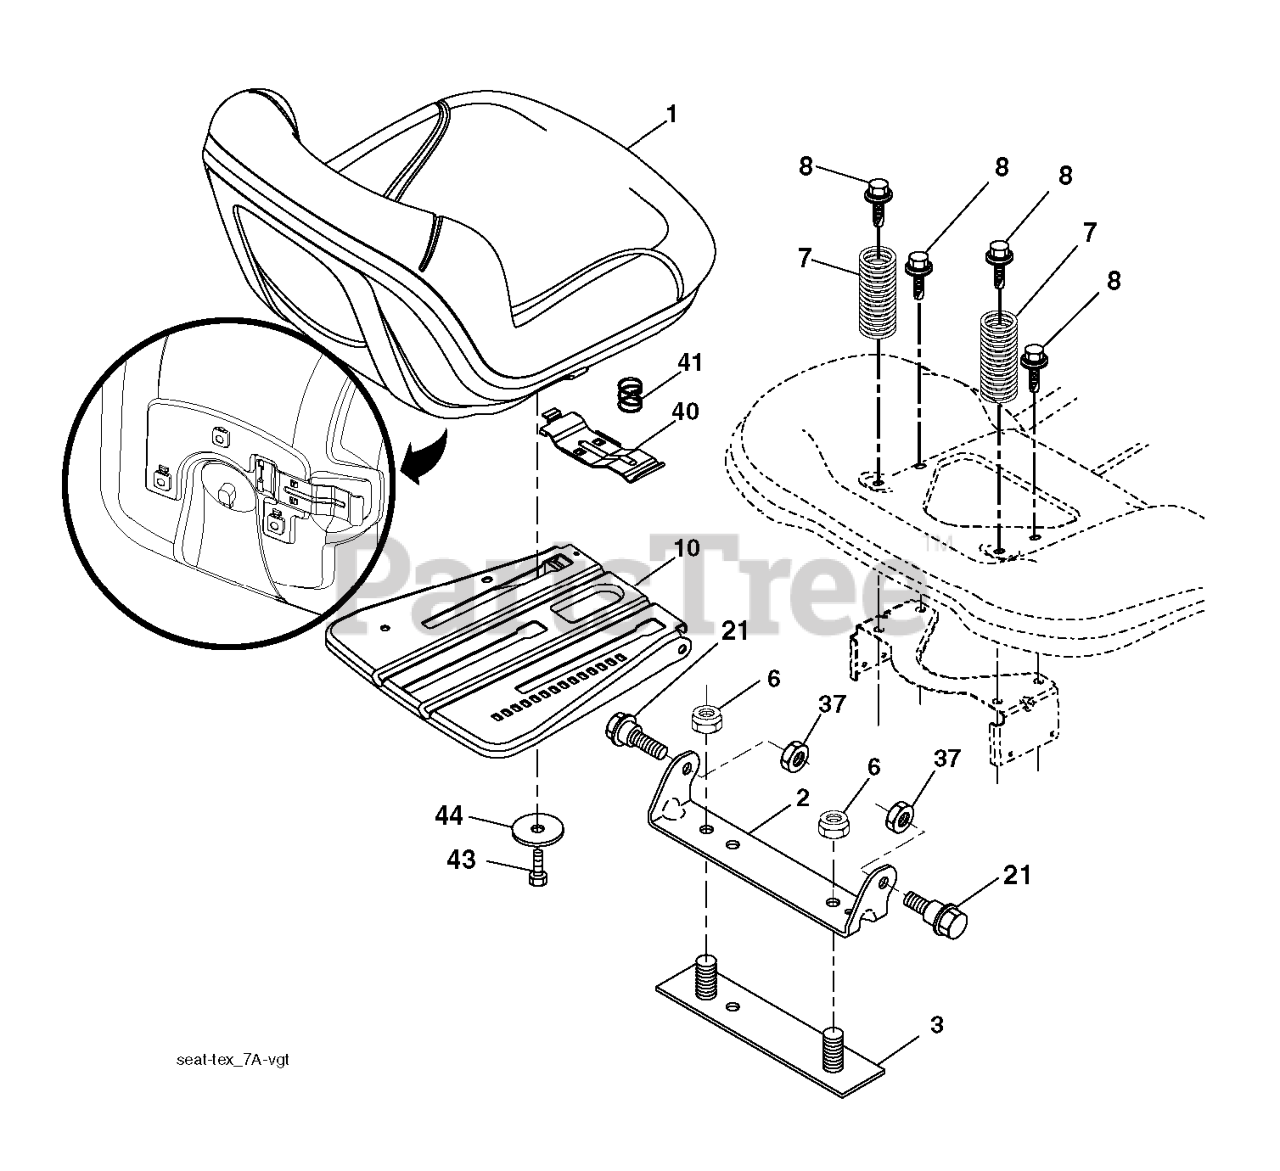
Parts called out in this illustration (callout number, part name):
1	RP SEAT.TH130.GRY.MILSCO.
2	BRKT.PIVOT.FENDER
3	STRAP
6	NUT
7	SPRING COMPRESSION
8	BOLT.5/16-18UNCX3/4 W/SEMS.BLK
10	PAN.ASM.SEAT.3PT
21	BOLT.SHOULDER.5/16-18
37	NUT.71038.31-18.HEX.NYLOCK
40	HANDLE.SLIDE.SEAT.TEX.BLACK
41	SPRING.LATCH.SEAT.TEX
44	WASHER 13/32 X 2-3/8 X 12GA
